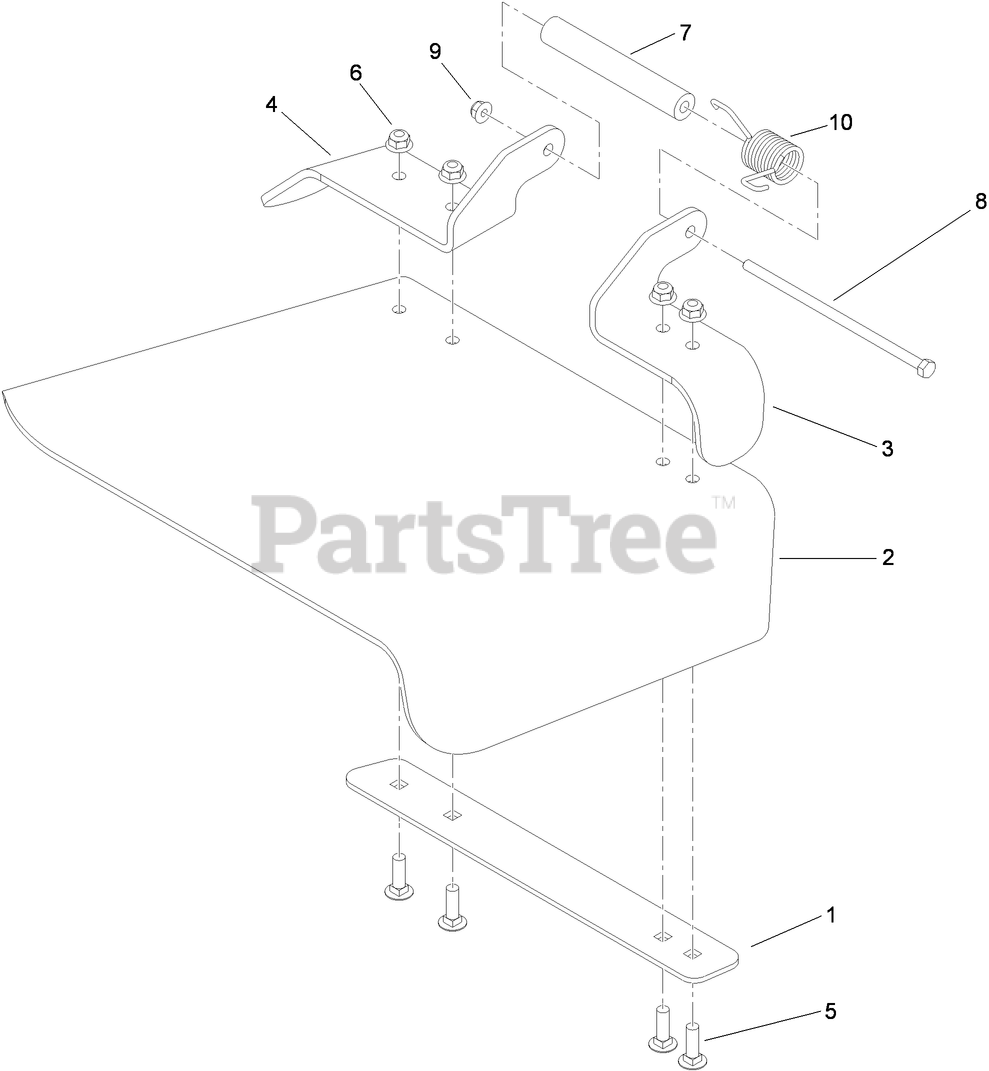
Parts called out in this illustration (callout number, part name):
1	STRAP-DISCHARGE
2	DEFLECTOR-RUBBER
3	BRACKET-HINGE, FRONT
4	BRACKET-HINGE, REAR
5	BOLT-CARR
6	NUT-HF, NI
7	SPACER
8	SCREW-HH
9	NUT-HF, NI
10	SPRING-TORSION
